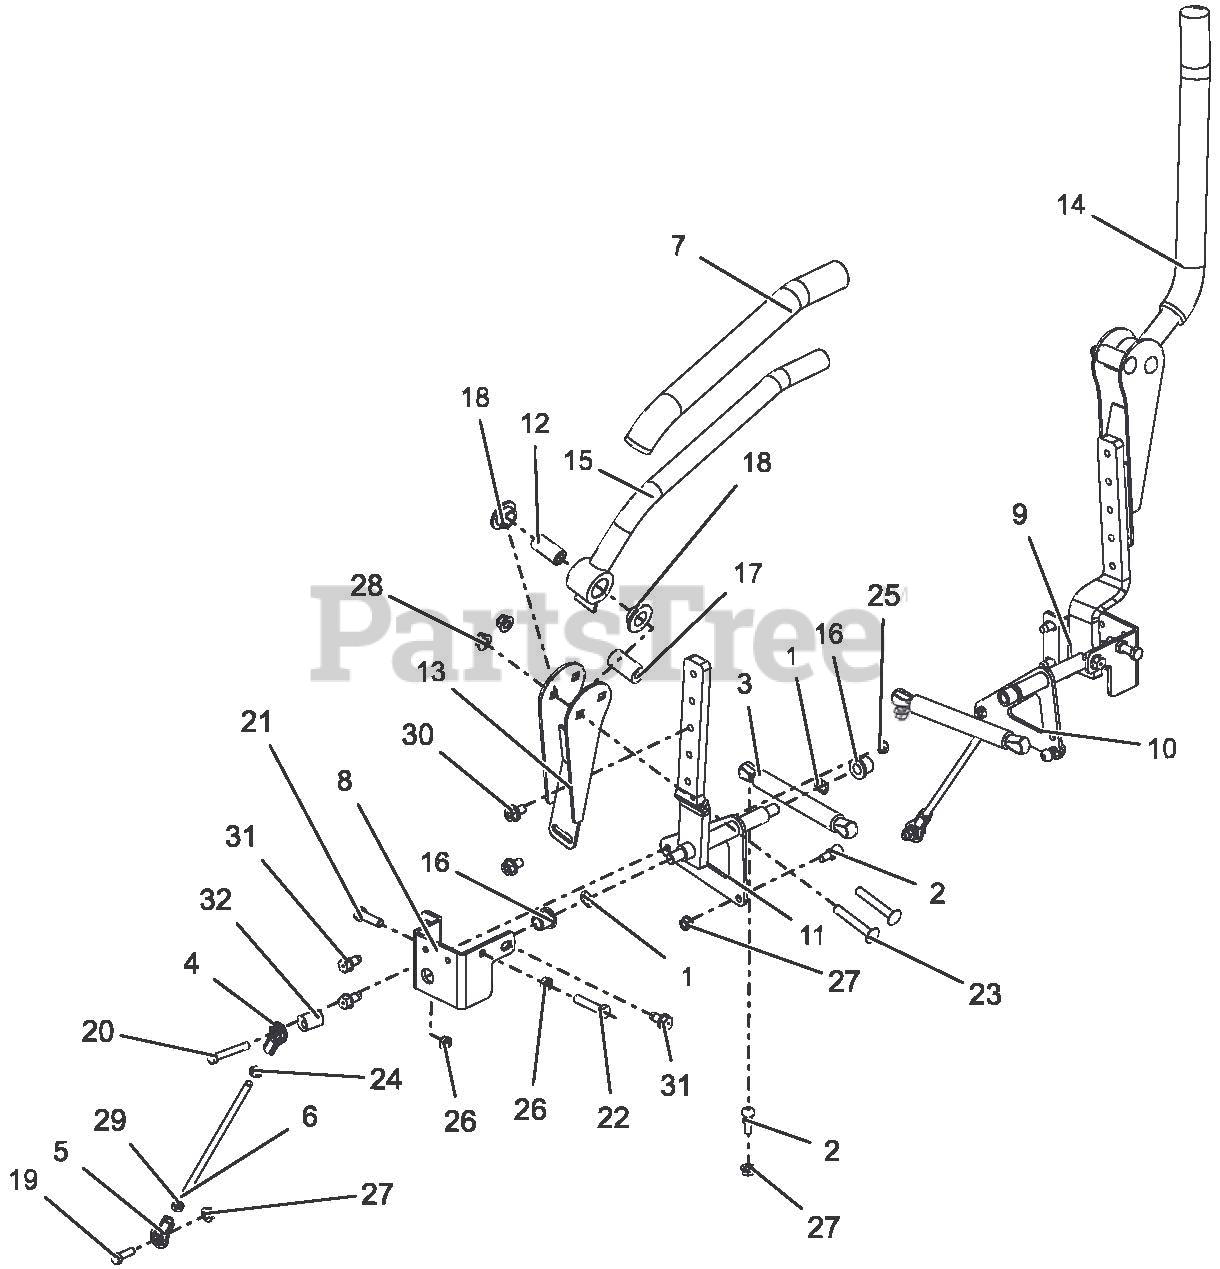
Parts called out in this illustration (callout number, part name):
1	WAVE WASHER .531 X .781 X .125 FH
2	STUD-BALL
3	DAMPER
4	ALIGNABALL, 5/16 RH THREAD
5	ALIGNABALL, 5/16 LH THREAD
6	ROD, STEERING
7	GRIP, HANDLEBAR
8	BRKT, RH CONTROL ARM STOP
9	BRKT, LH CONTROL ARM STOP
10	WLDMT, LH LOWER CONTROL ARM
11	WLDMT, RH LOWER CONTROL ARM
12	SPCR, STEERING ARM
13	WLDMT, UPPER ADJUSTABLE CONTROL ARM
14	WLDMT, LH CONTROL HANDLE
15	WLDMT, RH CONTROL HANDLE
16	BSHG-FLG .500 X .750 X .750 X .125
17	BSHG, ECCENTRIC .328 X .750 X 1.625
18	BSHG, FLANGE .762 X 1.48 X .44 NYLON
19	BLT-HEX .31-18 X 1.00 GR5 YWZC
20	BLT-HEX .31-18 X 2.00 GR5 YWZC
21	BLT-HEX .38-16 X 1.25 GR5 YWZC
22	BLT-HEX .38-16 X 1.75 GR5 YWZC
23	BLT-RHDSSQNK .38-16 X 2.50 G5YZ
24	NUT-HEX .312-24 YWZC
25	NUT-LK-CTR .31-18 YWZC
26	NUT, JAM .375-16 YWZC
27	NUT, LK-TOP-FLG .312-18 YWZC
28	NUT-LK-NYL-FLG .38-16 YWZC
29	NUT-HEX .312-24 LH GR5 YWZC
30	BLT-SERHFWH .38-16 X .62 YWZC
31	SCR-TAP .38-16 X .75 HWH TR YWZ
32	ECCENTRIC
